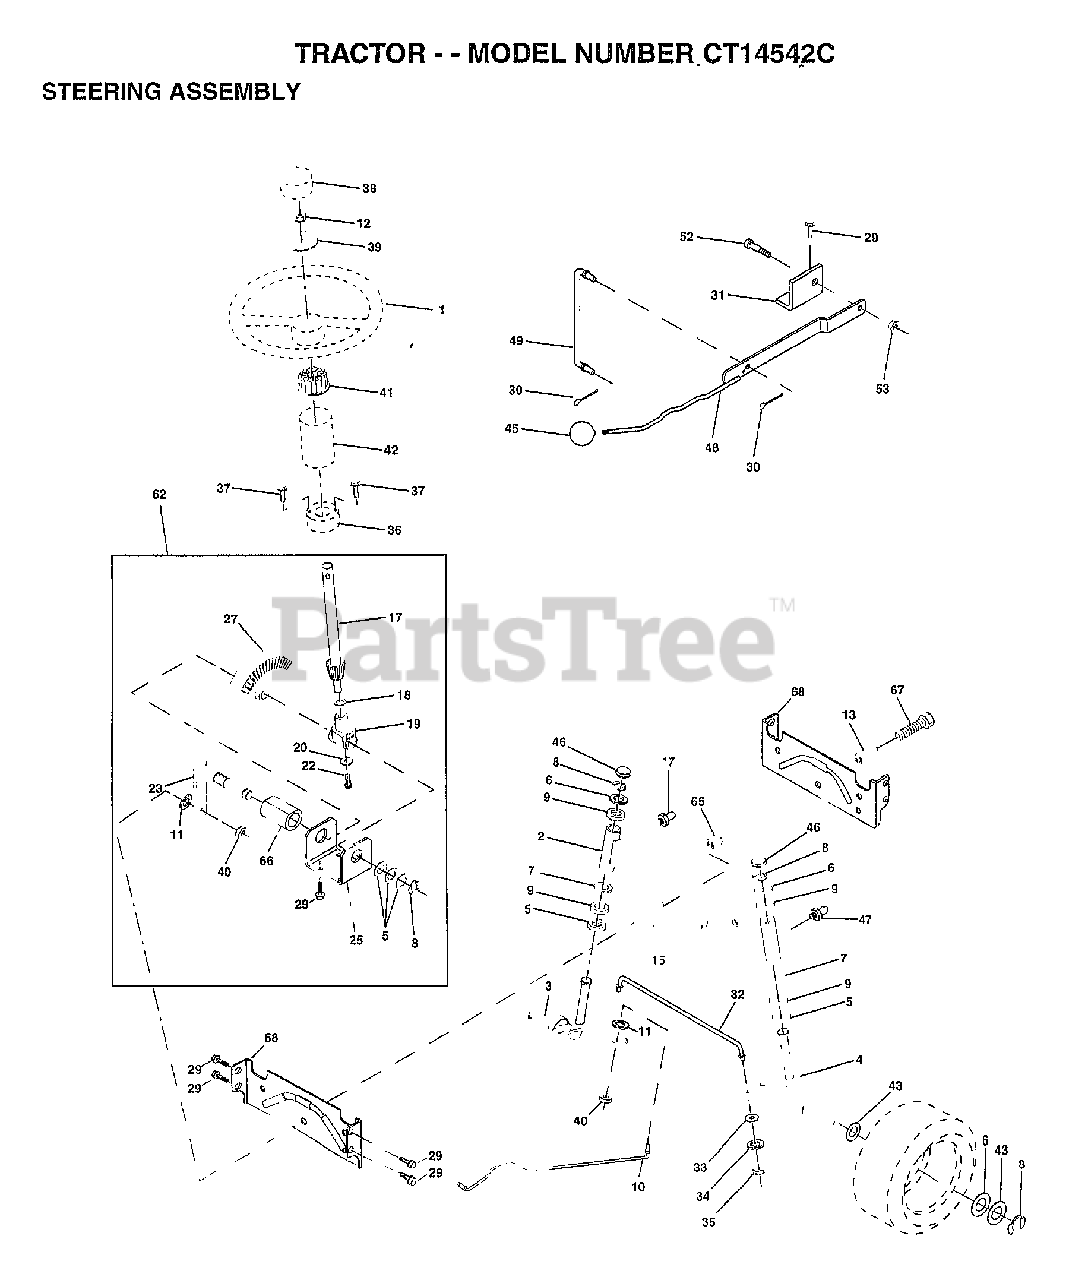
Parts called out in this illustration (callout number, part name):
1	WHEEL STR AYP BLK
2	AXLE ASM
5	WASHER .T
6	WASHER
7	WASHER
8	RING
9	COL. SRTG. BEAR.
10	DRAGLINK-STAMPED
11	LOCKWASHER
13	BEARING AXLE
15	"NUT-LOC,FLANGE LT"
17	SHAFT ASM STEERNG
18	THRUST WASHER
19	SUPPORT.SHAFT
21	LOCKWASHER
22	SCREW HEX SOC1/4-
25	BRKT-STEERING
27	GEAR SECTOR
29	SCREW
30	COTTER PIN
31	BRKT.PVT.MAN.LVR.
32	ROD.TIE.19.75
33	WASHER M
34	LOCKWASHER
35	NUT.LOCK.5/16-24
36	BUSHING.STRG.3/4
37	"SCREW-TT,10-32 FL"
38	CAP STEER AYP
39	WASHER
40	GRIPCO NUT
41	ADAPTER LT
42	BOOT SHAFT STEER
43	WASHER
45	KNOB T (1/2-HOLE)
46	CAP
47	ZERK M
48	LEVER.ASM.CLUTCH
49	LINK CLTCH W/NUTS
52	"BOLT, SHOULDER LT"
62	KIT STEERING ASM
65	SPACER AXLE
66	"BEARING-ARM,PITMA"
67	BOLT
68	BRACE AXLE
